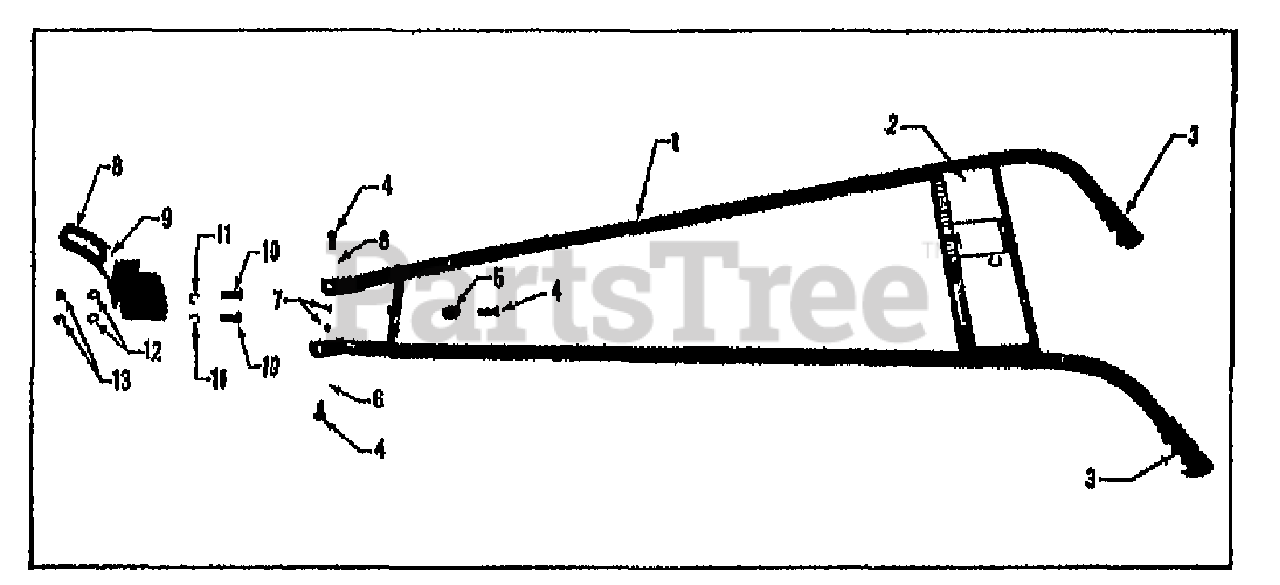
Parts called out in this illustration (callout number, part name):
1	ASSM-HANDLEBAR CULT (INCL. 60151 & 9471)
2	DECAL-CONTROL PANEL
3	GRIPS-HANDLEBAR
4	SCR-HH 3/8-16X1.0 G5 ZP (HANDLEBAR HEIGHT ADJ. ALSO MOUNTS HANDLEBAR TO CHASSIS)
5	WASHER-#1.75X.625X.120
6	WASHER-FLAT 3/8 SAE
7	NUT-LOCK 3/8-16 NYLON ZP
8	PLATE-H/B ADJ W/DECAL #60075
9	DECAL-HANDLEBAR ADJUST
10	SCR-HH 3/8-16X1.0 G5 ZP (ATTACHES HANDLE- BAR HEIGHT ADJ. PLATE TO CHASSIS)
11	WASHER-LK .375 @ DEPL
12	WASHER-.734X.375X.065 ZP
13	NUT-HEX 3/8-16 ZP
